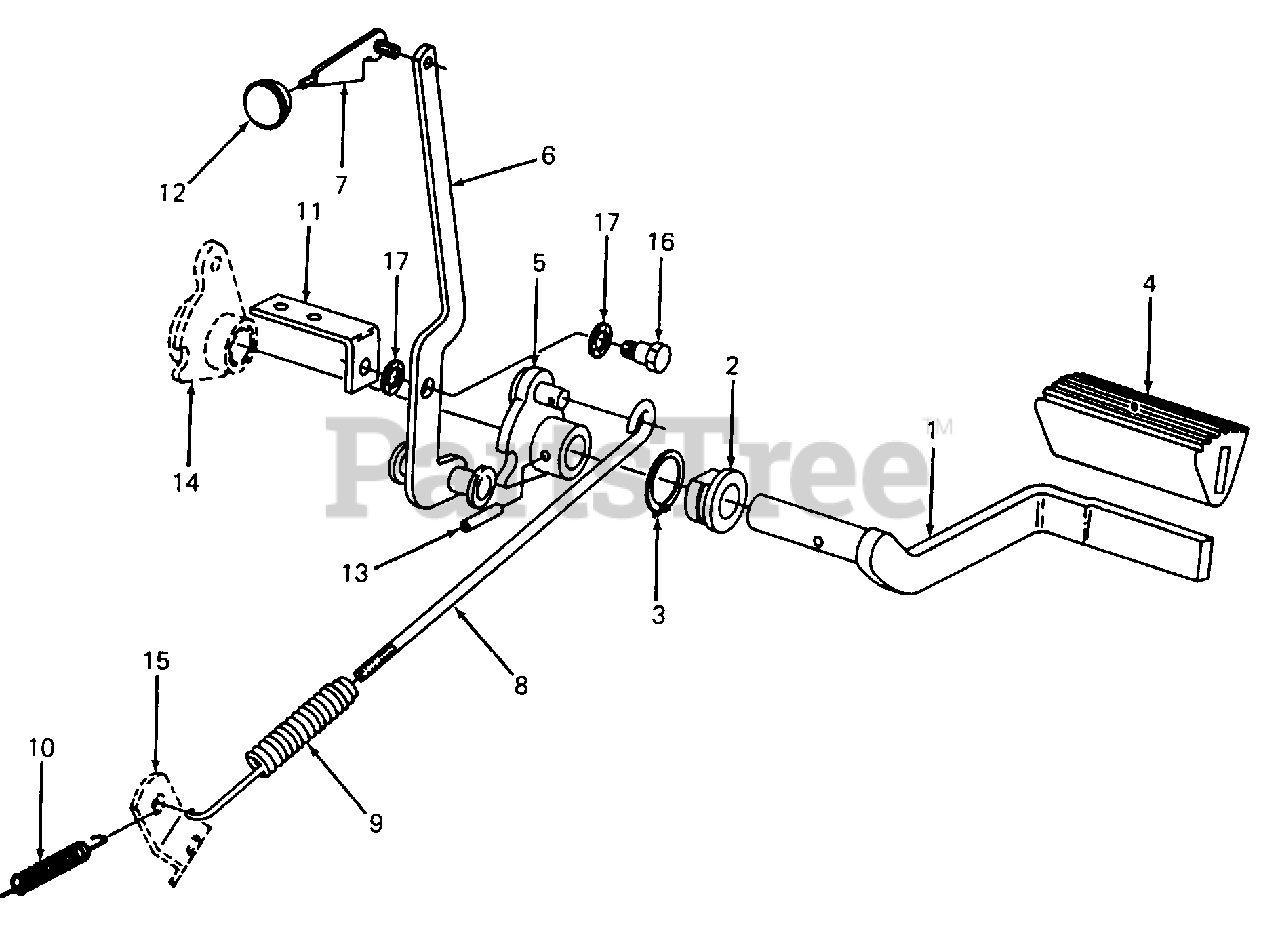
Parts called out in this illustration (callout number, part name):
1	Pedal, Brake
2	Bearing, Flanged
3	Ring, Retainer
4	Pad, Foot
5	Cam, Brake
6	Lever, Parking Brake
7	Handle, Brake Parking
8	Rod, Brake
9	Spring, Extension
10	Spring, Brake Return
11	Support, Brake Lockout
12	Knob, Brake Lock Handle
13	Pin, 1/4 X 1-1/4 Pln Slt-Spr
14	Cam, Clutch
15	Lever, Brake Part of Transaxle
16	Screw, Shoulder
17	Washer, .530 X .780 X .013 Wave
